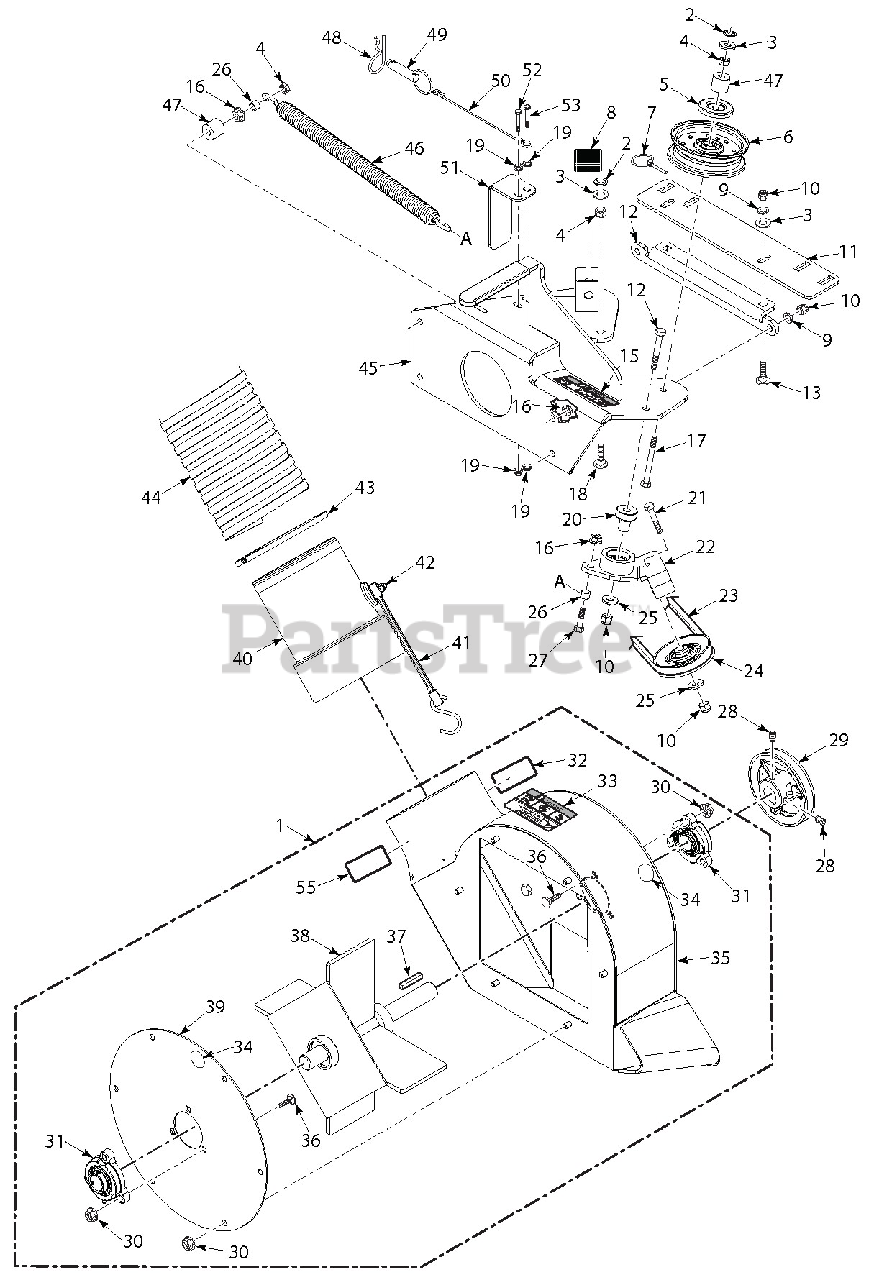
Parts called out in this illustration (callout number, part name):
1	Blowing Housing Assembly w/Fan
2	Nut, Push-On
3	Flatwasher, 3/8-.391 x .938 x .105
4	Nut, Center Lock 3/8-16
5	Dust Shield
6	Pulley, 4" Idler
7	Quick Pin
9	Lockwasher, 3/8" Spring
10	Nut, Elastic Stop 3/8-16
11	Plate, Blower Catch
12	Plate, Catch Mounting
13	Bolt, Carriage 3/8-16 x 1-1/4"
14	Bolt, Hex Head 3/8-16 x 2-1/4"
15	Decal, Belt Cover
16	Nut, Serrated Flange 3/8-16
17	Bolt, Hex Head 3/8-16 x 3-1/2" Full Thread
18	Bolt, Carriage 3/8-16 x 1-1/2"
19	Nut, Serrated Flange 1/4-20
20	Pivot, Idler
21	Bolt, Hex Head 3/8-16 x 2"
22	Idler Arm Assembly
22	Bearing
23	Belt (52)
23	Belt (61)
24	Pulley, 3-1/2" V-Groove
25	Flatwasher, 3/8-.391 x .938 x .105 HD
26	Sleeve
27	Bolt, Hex Head 3/8-16 x 1-1/4"
28	Set Screw
29	Pulley, 4-3/4" Dia.
30	Nut, Serrated Flange 5/16-18
31	Bearing Assembly
32	Decal, Blower
33	Decal, Danger
34	Decal, Grease Point
35	Blower Housing Weldment w/Decals
36	Bolt, Carriage 5/16-18 x 1"
37	Key, 1/4 x 1/4 x 1-1/2"
38	Fan Weldment, Narrow
39	Cover, Blower Housing
40	Adapter w/Strap
41	Rubber Strap
42	Bolt, Hex Head 1/4-20 x 1-1/4"
42	Nut, Elastic Stop 1/4-20
42	Flatwasher, 1/4-.312 x .750 x .065
43	Clamp, 6-1/2"
44	Hose, 6" x 56"
45	Blower Mounting Frame w/ Decal
46	Spring
47	Spacer
48	Hair Pin
49	Pin, Ring
50	Lanyard
51	Belt Cover
52	Bolt, Hex Head 1/4-20 X 1-1/2"
53	Bolt, Hex Head 1/4-20 x 1-1/4"
55	Decal, Rotating Blades
